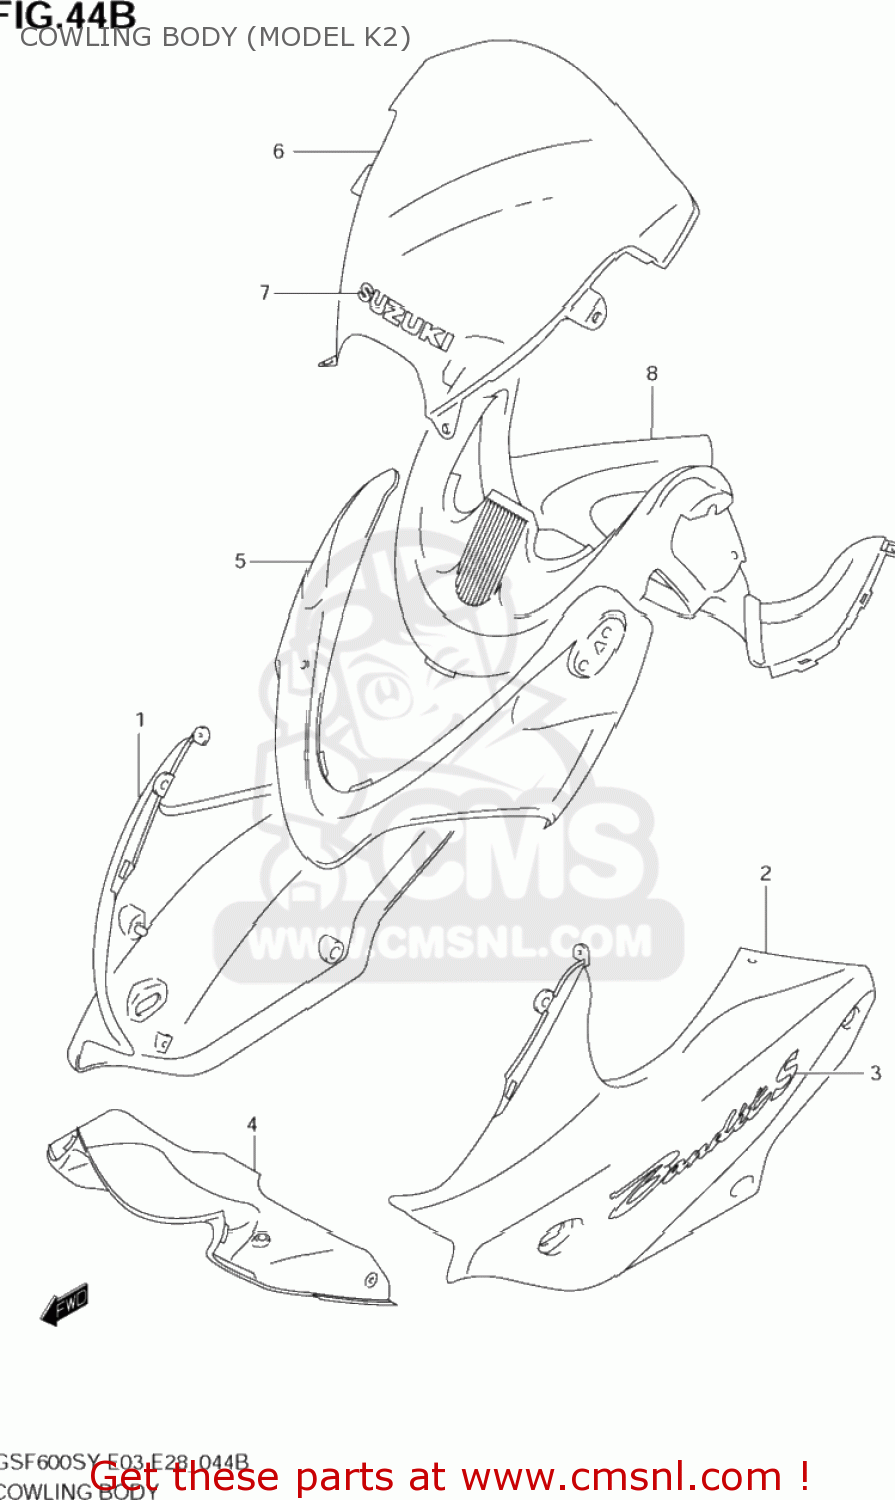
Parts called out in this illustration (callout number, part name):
1	COWLING ASSY,SIDE,R
2	COWLING ASSY,SIDE,L
3	EMBLEM,COWLING SIDE
4	COWLING,CTR(RED)
5	COWLING,FR
6	WINDSCREEN ASSY(SILVER)
7	EMBLEM,SUZUKI
8	PANEL,METER
